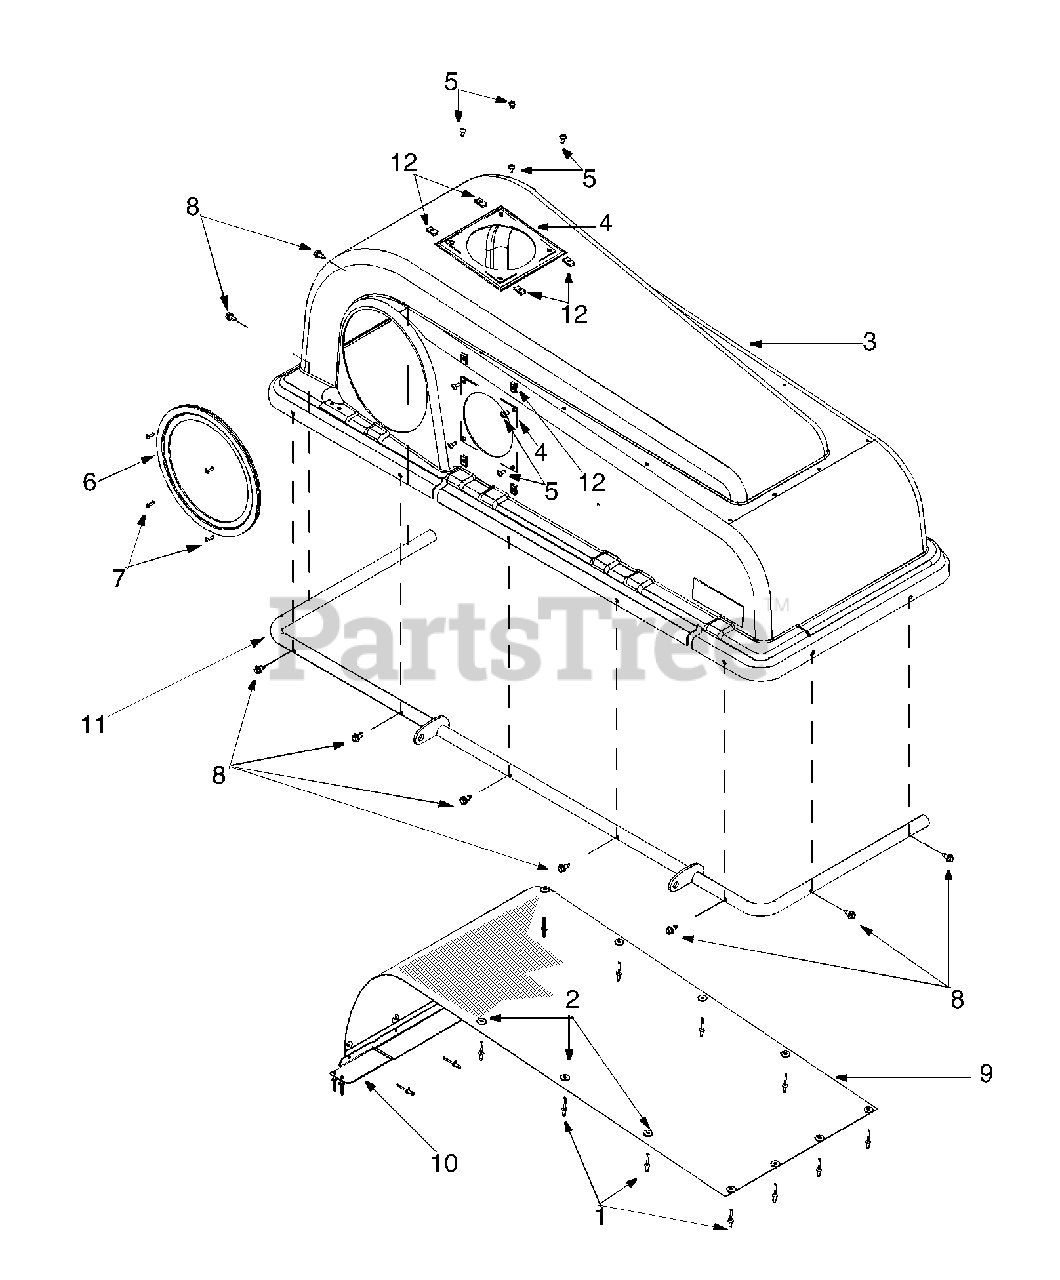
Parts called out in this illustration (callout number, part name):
1	Pop Rivet
2	Flat Washer 1/4" I.D.
3	Grass Catcher Cover
4	Plastic Plate
5	Truss Machine Screw #10 x 0.5" Lg.
6	Tube Seal
7	Truss AB-Tap Screw #6 x 0.6"
8	Hex AB Screw 1/4-14 x 0.625"
9	Screen
